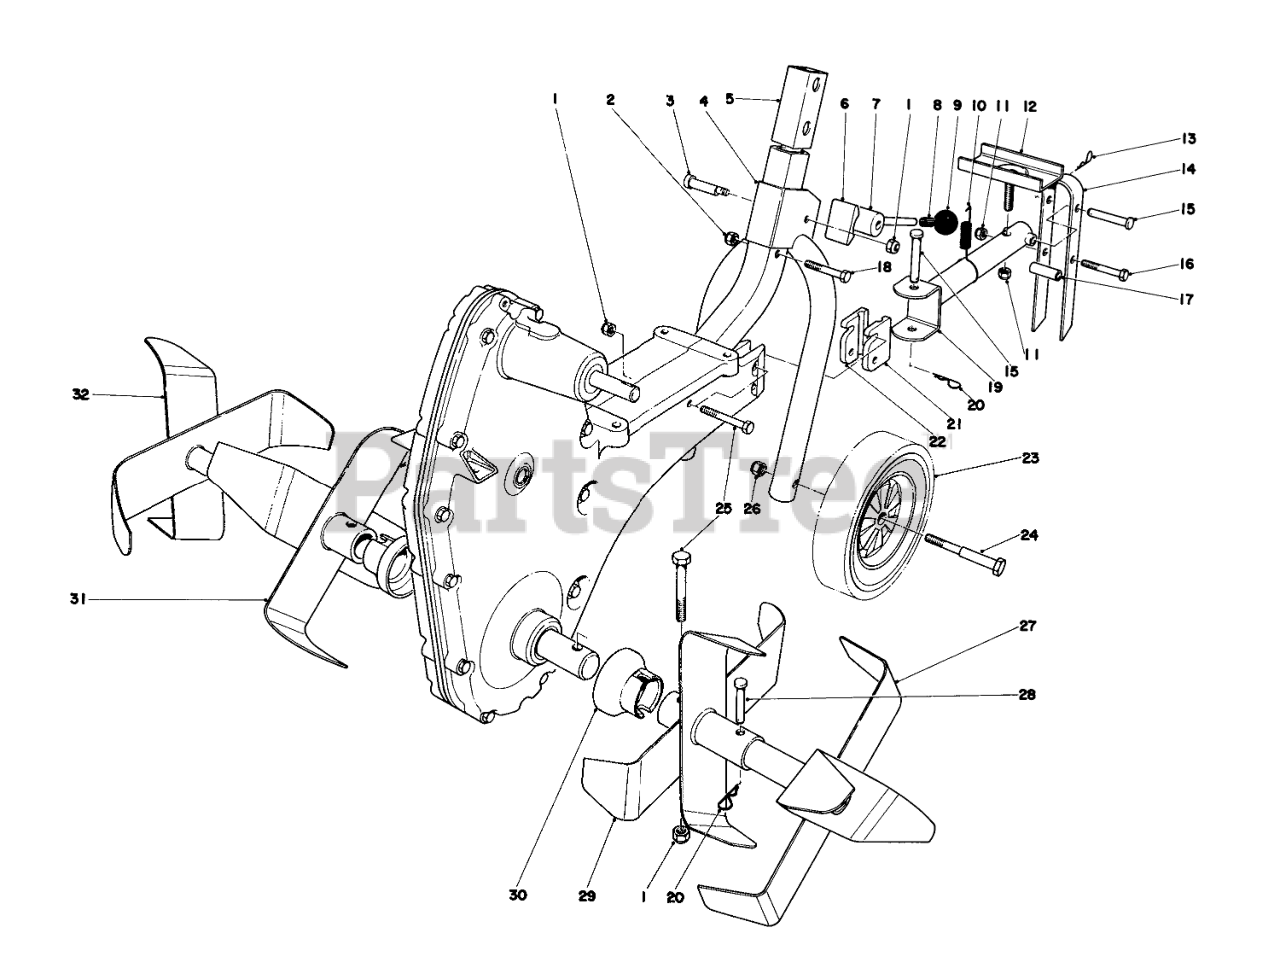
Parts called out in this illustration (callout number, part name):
1	NUT-HEX, SIDE DEFORM
2	Locknut
3	Cam Pivot
4	Wheel Support
5	Lower Handle
6	Cam Shoe
7	Cam Lever
8	Tolerance Ring
10	Spring
11	NUT-LOCK, SIDE
12	Drawbar Stop
13	HAIRPIN COTTER
14	Dragbar
15	PIN-CLEVIS
16	SCREW-HH
17	Spacer
18	SCREW-HH
19	Drawbar
20	PIN-COTTER, HAIR
21	Pivot Block L.H.
22	Pivot Block R.H.
23	WHEEL TIRE ASM 8 IN
24	Wheel Bolt
25	SCREW-HH
26	NUT-LOCK, CONE
27	Outboard Tine L.H.
28	CLEVIS
29	Inboard Tine L.H.
30	Dust Cover
31	Inboard Tine R.H.
32	Outboard Tine R.H.
